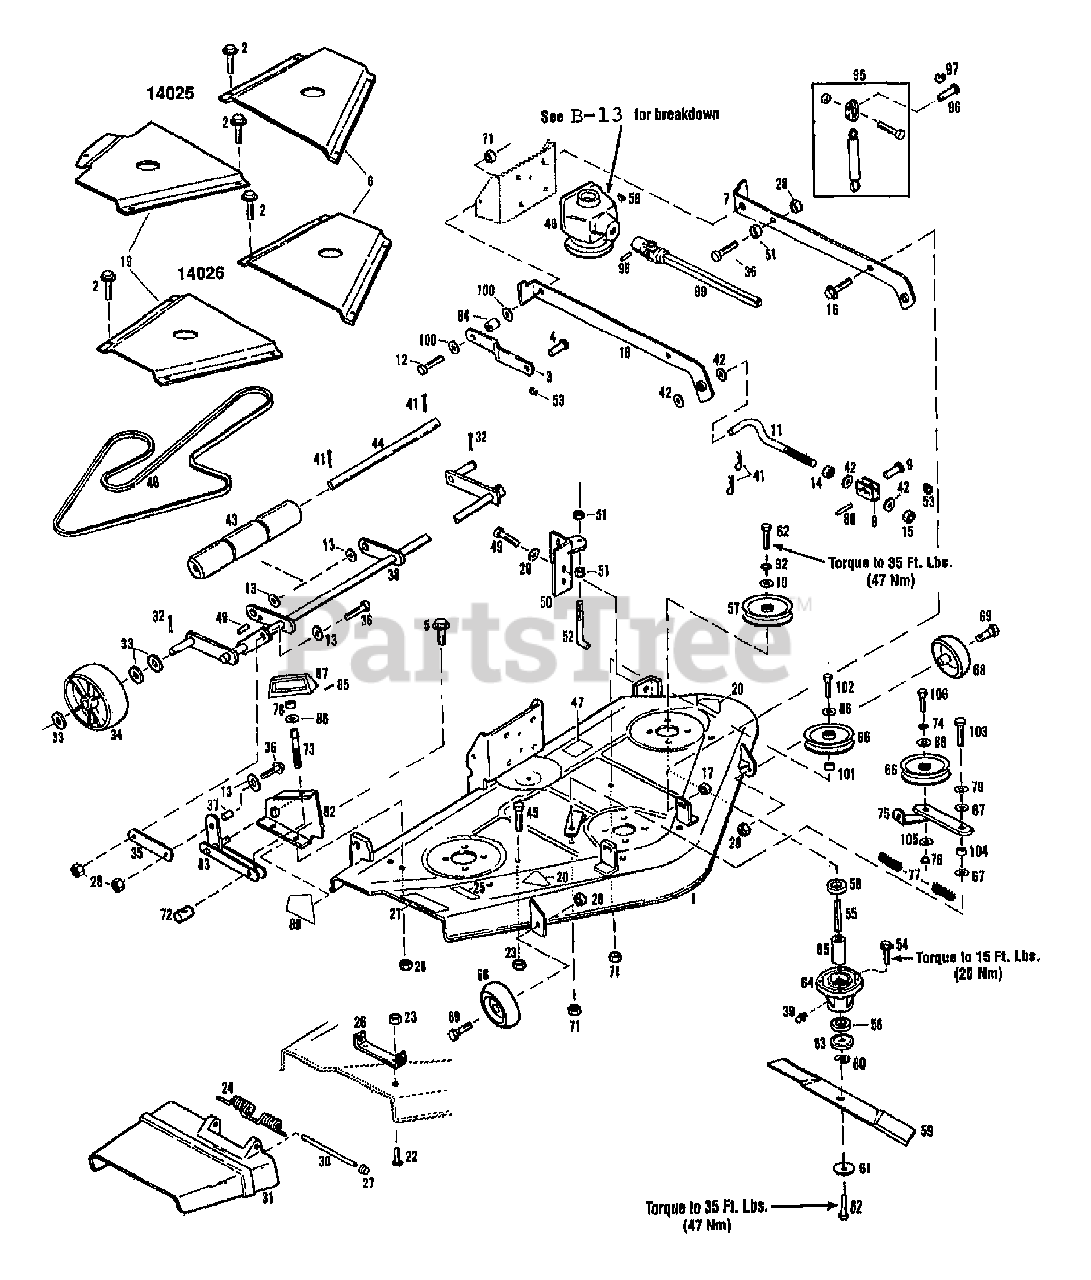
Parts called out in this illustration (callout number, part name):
1	BASE-MOWER W/DECALS {14025}
1	BASE-MOWER W/DECALS {14026}
2	SCR 1/4-20X.5 FL SELF TAP
3	LINK-DRAG
4	PIN-CLEVIS .625X1.44
6	COVER-BELT LH {14025}
6	COVER-BELT LH {14026}
7	SUPPORT-DECK LH
8	BRKT-HITCH
9	PIN-CLEVIS .62X2.50 ZP
10	WASHER-1.25X.5X.083 ZP
11	LINK-HITCH
12	SCR-HH 1/2-13X1.75 G5 ZP
13	WASHER-FLAT 3/8 SAE
14	NUT
15	NUT-H/LK 3/4-10
16	SCR-HFLK 3/8-16X1.00 ZP
17	NUT-HFLK 3/8-16 ZP
18	SUPPORT-DECK RH
19	COVER-BELT RH {14025}
19	COVER-BELT RH {14026}
20	DECAL-OPEI CAUTION
21	DECAL-DANGER
22	BOLT-CARR 5/16-18X.63 ZP
23	NUT-TOP/LK 5/16-18 ZP
24	SPRING-TORSION
25	DECAL-CUTTING LINE
27	NUT-PUSH 3/8 ZP
28	NUT-LOCK 3/8-16
29	WASHER-1.12X.378X.125
31	DEFLECTOR-DISCHARGE
32	PIN-COTTER .120X1.00 ZP
33	WASHER-1.06X.531X.1 ZP {14025}
33	WASHER-1.305X.649X.098 ZP {14026}
34	WHEEL-GAGE {14025}
34	WHEEL-GAGE {14026}
35	LINK-CONNECTING {14025}
35	LINK-CONNECTING {14026}
36	SCR-HH 3/8-16X1.5 G5 ZP
37	SPACER-.625X.39X.343
38	SHAFT-PIVOT {14026}
39	FITTING-GREASE 1/4-28X2.00
40	PIN-ROLL 1/8 X 3/4
41	PIN-COTTER .120X1.25 ZP
42	WASHER-1.38 X.765X .06 ZP
44	AXLE-ROLLER
45	SCR-HH 5/16-18X1.25 G5ZP
46	ASSM-GEAR CASE
47	DECAL-BELT DRIVE
48	BELT {14025}
48	BELT-V {14026}
49	SCR-HH 3/8-16X1.0 G5 ZP
50	SUPPORT-SHAFT
51	NUT-HEX/JAM 3/8-16 ZP
52	BOLT-HOOK
53	RING-COTTER
54	SCR-HFLK 5/16-18X.75
55	SHAFT-SPINDLE
56	KEY-WOODRUFF .188X.75
57	ASSM-SHEAVE DRIVE
58	BEARING-BALL
59	BLADE-LIFT {14025}
59	BLADE-LIFT {14026}
60	RING-RETAINING EXT .694 ID
61	WASHER-BELLEVILLE
62	SCR-HH 1/2-14X1.00
63	SPACER-BLADE
64	HOUSING-SPINDLE
66	PULLEY-IDLER
67	WASHER
68	SHAFT-PIVOT {14025}
68	WHEEL-GAGE
69	SCR-SHLDR 3/8-16
71	NUT-TOP LOCK 1/2-13 ZP
72	PIVOT-ADJUSTING SCR
73	ROD-ADJUSTING
74	WASHER-LK .5 {14025}
75	ARM-IDLER {14025}
75	ARM-IDLER {14026}
76	BUTTON-WEAR
78	SPACER-HANDLE
79	WASHER-1.06X.531X.1 ZP
82	ASSM-ADJ BRKT
83	ASSM-ADJ ARM
85	PIN-ROLL .188X1.0
86	WASHER-FLAT .88X.5X.06 ZP
87	HANDLE-HEIGHT ADJ
88	PIN-DRIVE
89	DECAL-HEIGHT ADJUST
92	WASHER-LK .438 ZP
95	KIT-CHAIN
96	PIN-CLEVIS
97	RING-CIRCLE COTTER
98	PIN-DRIVE
99	ASSM-DRIVESHAFT
100	WASHER-1/2 FLAT
101	SPACER-TUBULAR
102	SCR-HH 1/2-13X2.0 G5 ZP
103	SCR-HH 1/2-13X1.5 G5 ZP
104	SLEEVE-BEARING
105	WASHER-.505X.22X.05
106	SCR-HH 1/4-20X1.25 G5 ZP
107	PAINT-BLACK SPRAY
